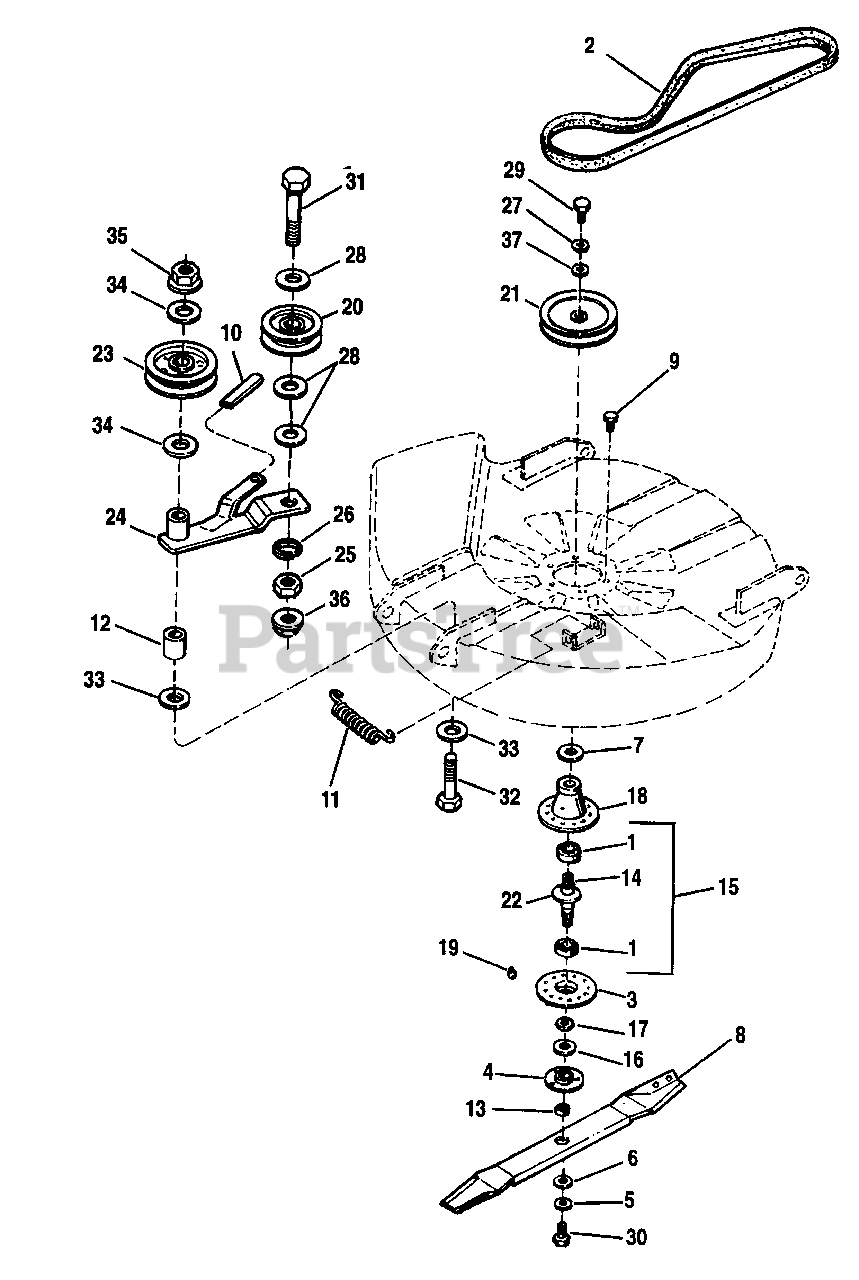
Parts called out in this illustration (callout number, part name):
2	V-BELT, 73-7/64"
3	COVER, Arbor Housing
4	ADAPTOR, Blade
5	WASHER, Spring
6	WASHER, Spline
7	SHIELD, Bearing Upper, Arbor
8	BLADE, Mower, 30"
9	SCREW, Taptite, 5/16-18 x 3/4
10	GRIP, Lever
13	COLLAR, Mower Arbor
14	SHAFT, Arbor (Incl. Ref. No. 13)
15	SHAFT & BEARING ASSY. (Incl. Ref. Nos. 1 & 14)
16	SHIELD, Grass, Bottom
17	WASHER, Shim
18	ARBOR HOUSING ASSY. (Incl. Ref. No. 19)
19	FITTING, Grease
20	IDLER, Backside
21	PULLEY ASSY., 7-55/64" Dia.
22	GASKET, Foam
23	PULLEY ASSY., Idler, 6" Dia.
24	LEVER ASSY.
25	NUT, Hex, 3/8
26	LOCKWASHER, 3/8
27	LOCKWASHER, 7/16
28	WASHER, Flat, 13/32 x 1 x 1/8
29	CAPSCREW, Hex Hd., 7/16-14 x 1-1/2, Gr. 8
30	CAPSCREW, Hex Hd., 7/16-14 x 1, Gr. 8
31	CAPSCREW, Hex Hd., 3/8-16 x 2
32	CAPSCREW, Hex, 3/8-16 x 3
33	WASHER, Flat, 3/8 x 1-1/2 x 1/8
34	WASHER, Plain, 3/8
35	NUT, Hex, Whizlock, 3/8-16
36	NUT, Hex, Top Lock, 3/8-16
37	WASHER
